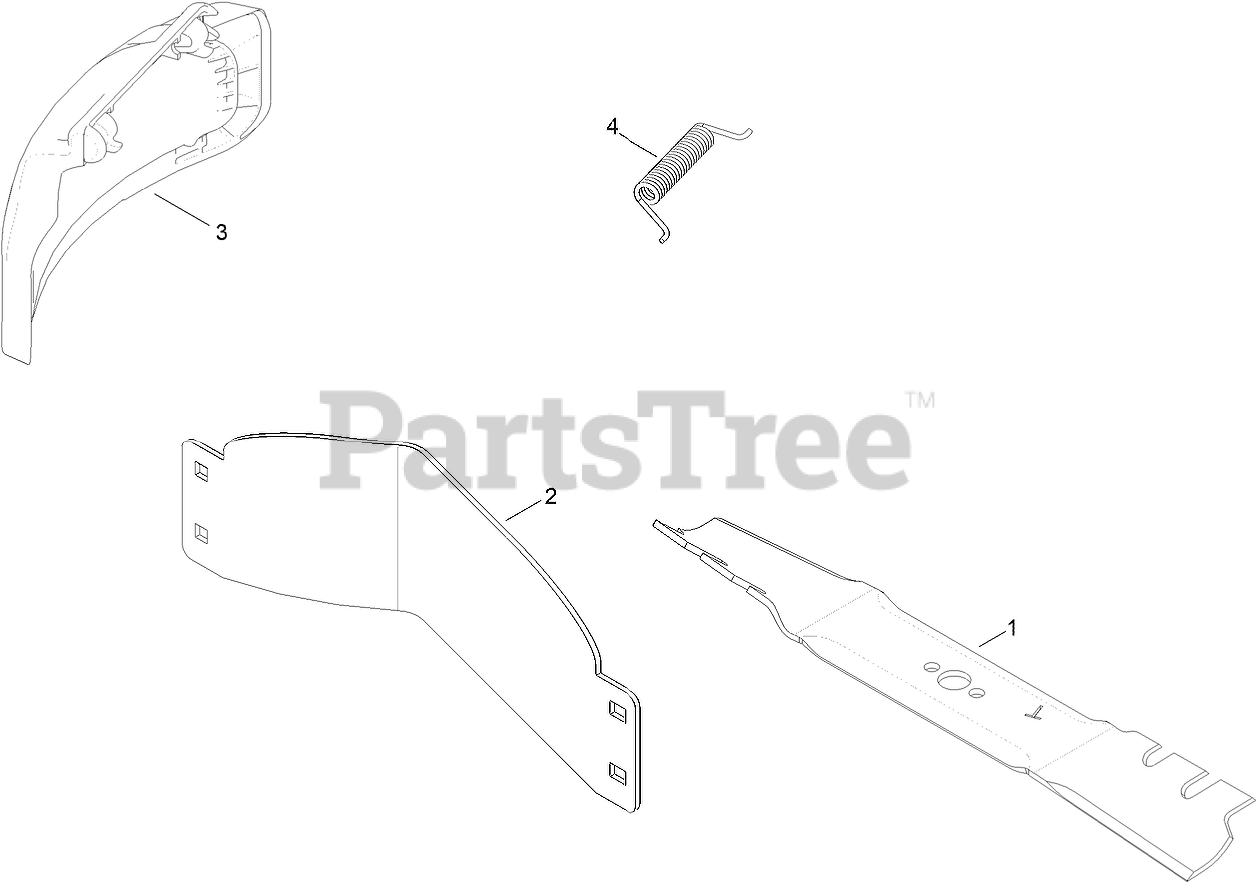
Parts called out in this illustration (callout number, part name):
1	BLADE ASM
2	BAFFLE-FLOW, CONTROL
3	DEFLECTOR-SIDE
4	SPRING-TORSION, COVER
